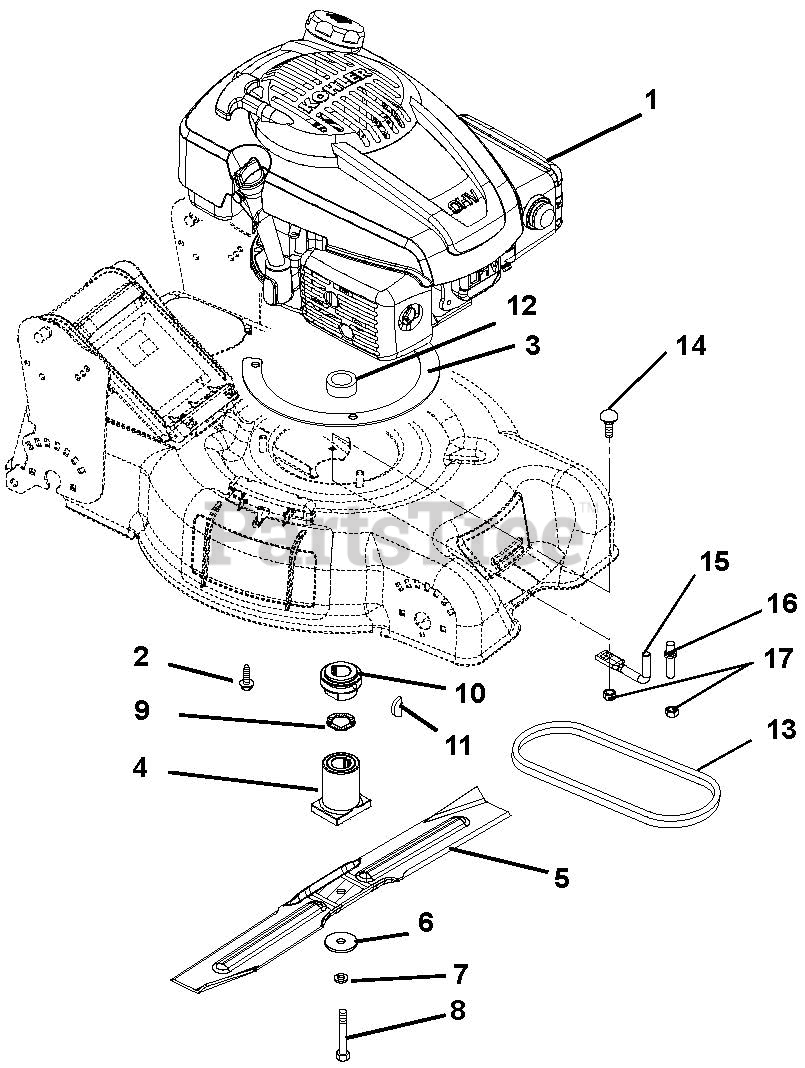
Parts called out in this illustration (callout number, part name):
1	ENGINE, KOHLER XT-7 BASE
1	ENGINE, KOHLER XT-7 CARB
1	ENGINE, HONDA GCV EL START
2	@SCR-TAP .38-16X1.00 HWH TR YZ
3	RING, ENGINE BOLT
4	ADAPTER, BLADE HUB
4	ADAPTER, 1" HONDA CRANK BLADE
5	21" MOWER BLADE
6	WSHR-FL-STL .390X1.5X.125 YWZC
7	@WSHR-LK .38X.094 REG YWZC
8	BOLT, 3/8-24X2.5 G8
8	BLT-HEX .62-11X3.00 GR8 YWZC
9	WASHER-WAVE .885X1.311X.125
9	WASHER - WAVE 1.09X1.37X.016
10	PULLEY-SINTERED IRON LM
10	PULLEY, 1" HONDA CRANK DRIVE
11	KEY-WDRF .156X.625X.25 SAE 6
11	KEY-WDRF .188X.625X.25 SAE 61
12	SPACER, .875X1.125X.551
12	SPACER, HONDA ELEC START CRANK
13	V-BELT, 3L-WRAPPED
14	@BLT-RDHDSQNK .25-20X.50 G5YZ
15	FINGER, BELT
16	FINGER, BELT
17	@NUT-SPNLK-FLG .25-20 YWZC
